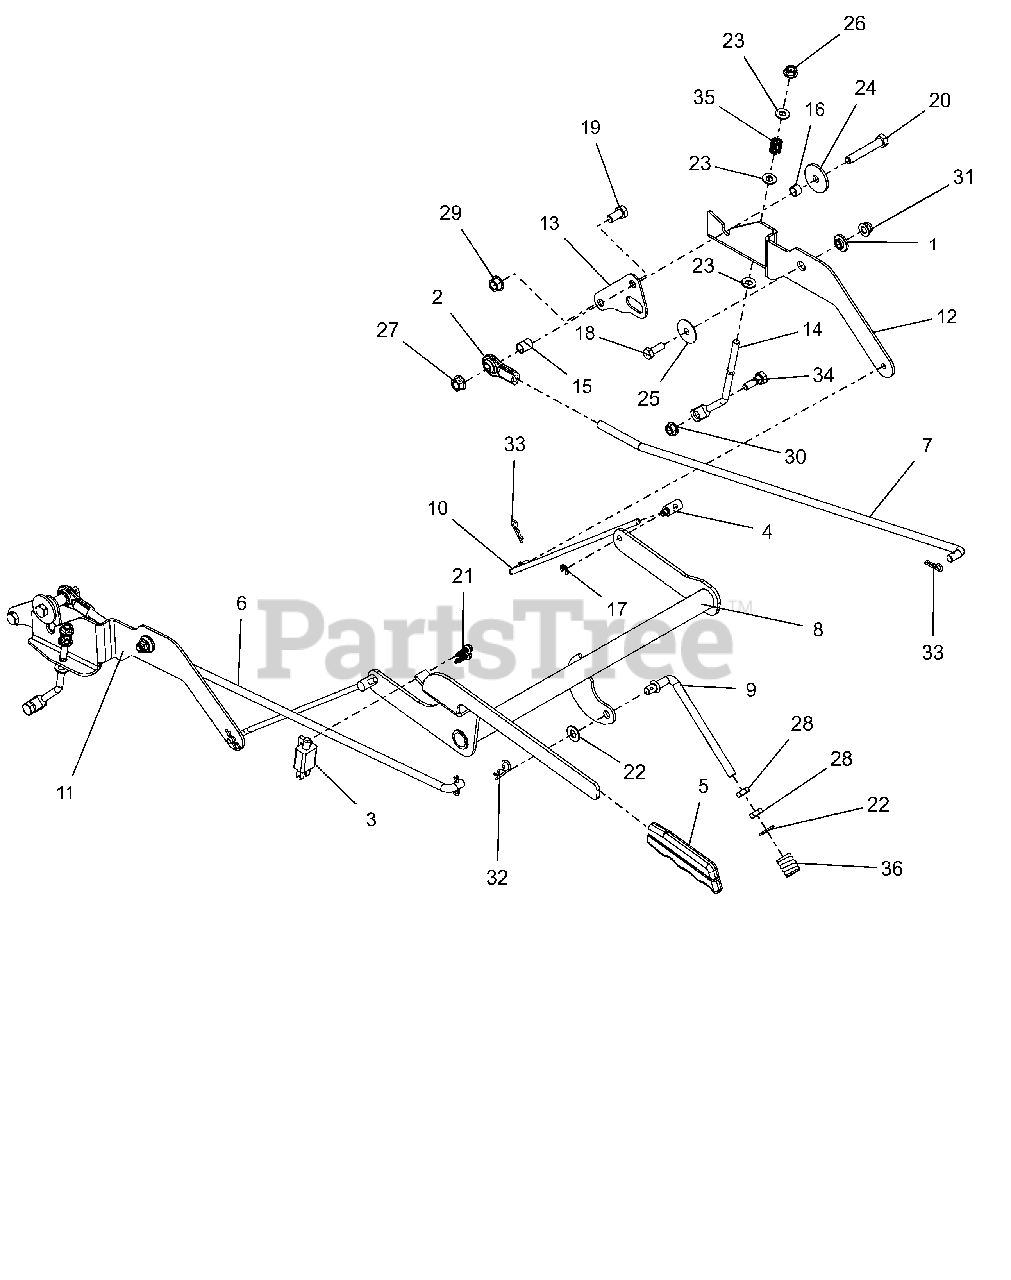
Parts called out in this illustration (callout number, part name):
1	BSHG, FLG .325X.499X.26X.88
2	ROD END, .38 RH
3	SWITCH- DOUBLE POLE N.O./N.O.
4	TRUNION, 1/4-20
5	GRIP, PARKING BRAKE (YELLOW)
6	STEERING, LINKAGE RH
7	STEERING, LINKAGE LH
8	WLDMT, BRAKE LEVER
9	LINK, OVER CENTER, PARKING BRK
10	ROD, PARK BRAKE
11	INTERLOCK, RH BRAKE LINK
12	INTERLOCK, LH BRAKE LINK
13	PLATE, TRANSAXLE ADAPTOR
14	LINK, TRANSAXLE BRAKE
15	SPCR, SLV .385X.500X.652
16	SPCR, SLV .385X.500X.350
17	RG-RTNG-EXT .250X.025
18	BOLT-HEX.31-18X.875 YWZC GR5
19	@BLT-HEX .38-16X.75 GR5 YWZC
20	@BLT-HEX .38-16X2.25 GR5 YWZC
21	SCR-TAP #12X.75 BOSS INDHXHD
22	@WSHR-FL-STL.406X.812X.065 YWZ
23	@WSHR-FL-STL.344X.688X.065YWZC
24	WSHR-FL-STL .380X1.50X.125YWZC
25	WSHR-FL-STL .347X1.254X.048YWZ
26	@NUT-LK-CTR-FLG .31-18 YZ GR F
27	NUT-LK-CTR-FLG .38-16 YWZC
28	NUT-HEX-JAM .375-16 YWZC
29	@NUT-LK-TOP-FLG .38-16 YWZC
30	@NUT-LK-TOP-FLG .31-18 YWZC
31	@NUT-LK-NYL-FLG .31-18 YWZC
32	PIN-HAIR CTR .09 X 1.50 YWZC
33	PIN-HAIR INT .08X.18X1.18 YWZC
34	BOLT,SHLDR .38X.25 -.31-18X.75
35	SPRING, COMPRESSION
36	SG-COMP .187X.56X1.62
